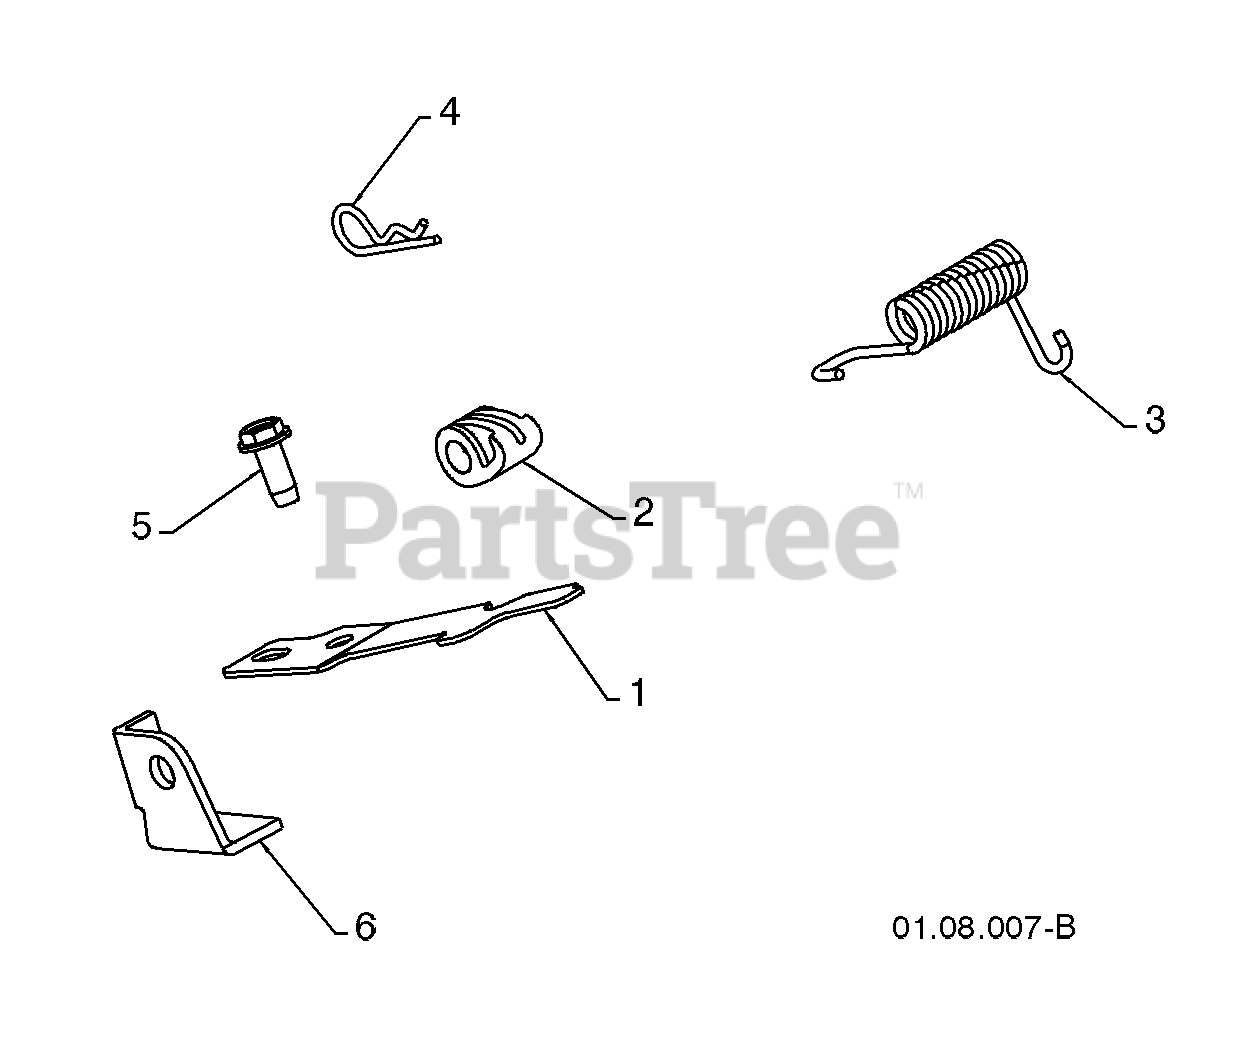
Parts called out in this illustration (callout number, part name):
1	INTERLOCK SPRING
2	INTERLOCK CAM
3	TORSION SPRING
5	SCREW 1/4-20 X .625
6	INTERLOCK STOP
